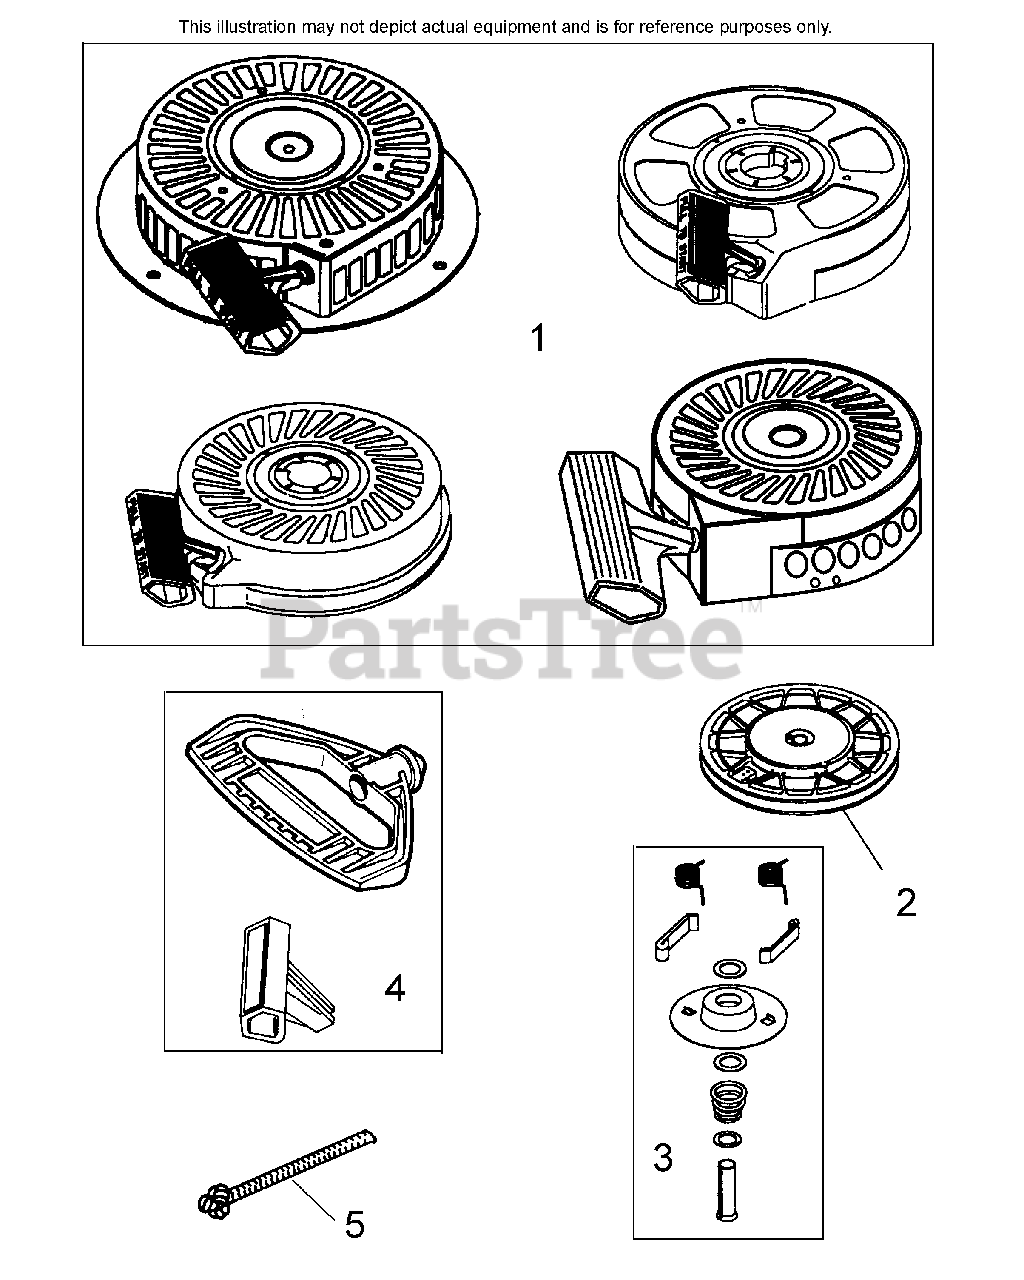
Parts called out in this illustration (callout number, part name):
1	"Rewind Starter Winter Pulley - (Mitte n Grip not incl.)
2	Pulley Assy Winter
3	Repair Kit
4	Starter Handle (Mitten Grip) also ava ilable in Packaged Part #740053B
5	98" Starter Rope (cut to length)
